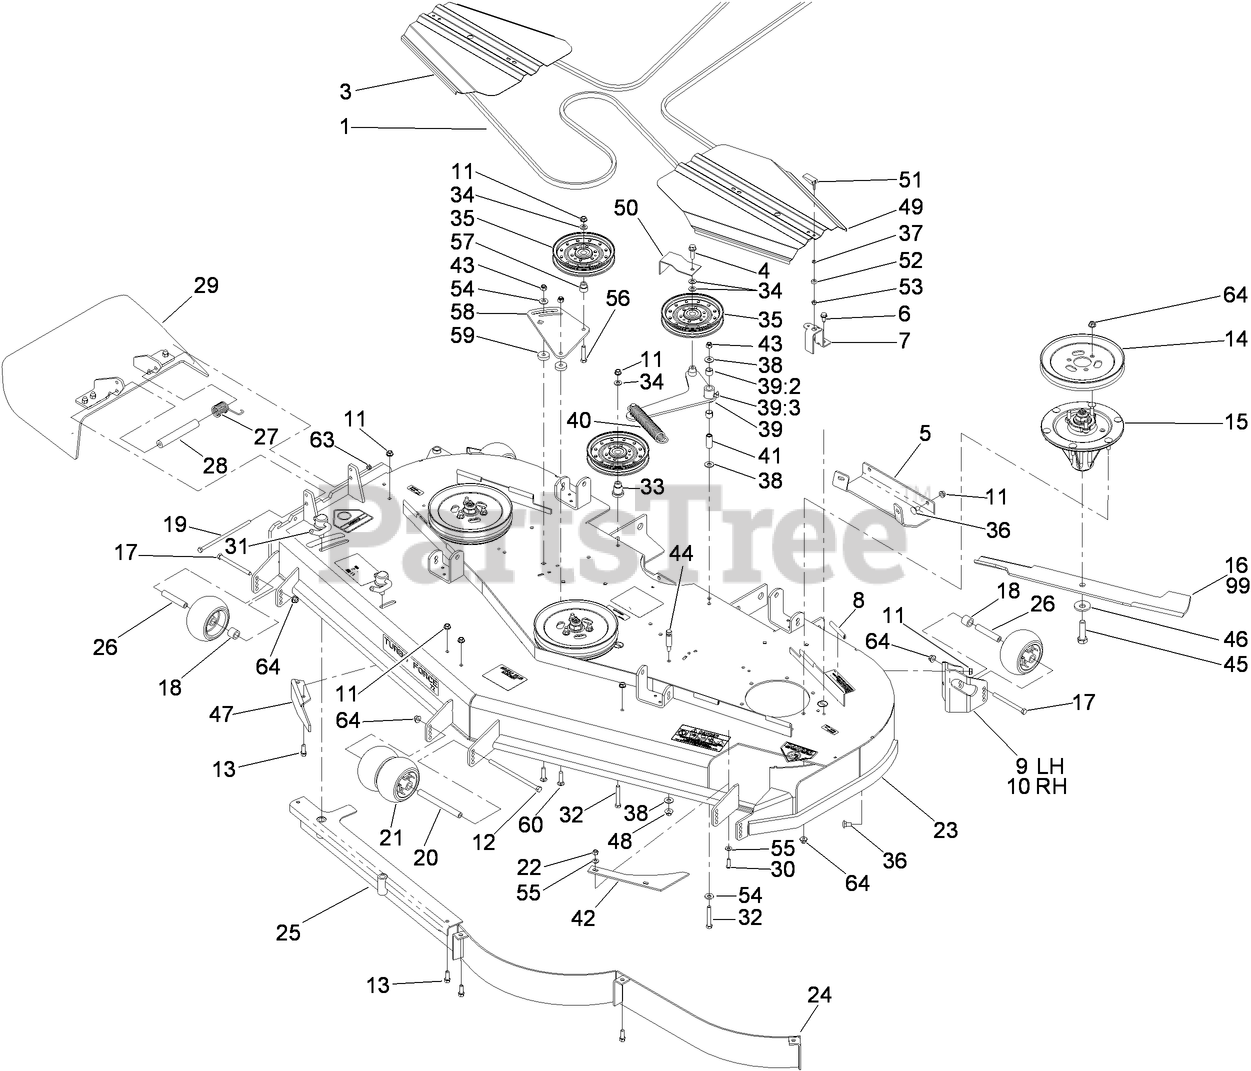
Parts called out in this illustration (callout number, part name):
3	COVER-BELT, RH
4	SCREW-HHF
5	Plate-Skid
6	SCREW-HWHTF
7	BRACKET-COVER
8	STRIP-SEAL
9	MOUNT-WHEEL, LH
10	MOUNT-WHEEL, RH
11	NUT-HHF, WHIZ
12	SCREW-HH
13	SCREW-HWH
14	Pulley
15	SPINDLE ASM
16	BLADE-HI FLOW, 24.5 INCH
17	SCREW-HH
18	TUBE-SPACER
19	SCREW-HH
20	SPACER-WHEEL
21	ROLLER-SCALP, ANTI
22	NUT-LOCK, NI
23	DECK DECAL ASM
26	TUBE-SPANNER
27	SPRING-TORSION
28	SPACER
29	RUBBER DEFLECTOR ASM
30	SCREW-HSBH
31	LEVER ASM
32	SCREW-HH
33	MOUNT-PULLEY
34	WASHER-FLAT
35	Idler-Flat
36	SCREW-CARR
37	WASHER
38	WASHER-FLAT
39	DECK IDLER ARM ASM
39:2	SLEEVE-BEARING
39:3	FITTING-GREASE, 90 DEG
40	SPRING-EXTENSION
41	BUSHING
42	PLATE-TURBO
43	NUT-LOCK, NI
44	PIN-THREADED, SPRING ANCHOR
45	SCREW-BLADE
46	Washer-Blade Bolt, Heavy
47	BAFFLE-DISCHARGE
48	NUT-HF
49	COVER-BELT, LH
50	GUIDE-BELT
51	HANDLE-LATCH, SWELL
52	BUSHING-LATCH, SWELL
53	NUT-LOCK, HH
54	WASHER-BELLEVILLE
55	WASHER-SPRING
56	SCREW-HH
57	BUSHING-IDLER
58	Plate-Idler
59	Spacer
60	SCREW-CARR
63	NUT-LOCK, NI
64	NUT-HF, NI
99	BLADE-RECYCLER, 24.5IN
99	BLADE-ATOMIC, 24.5IN
99	BLADE-LO FLOW, 24.5IN
99	BLADE-MID FLOW, 24.5IN
